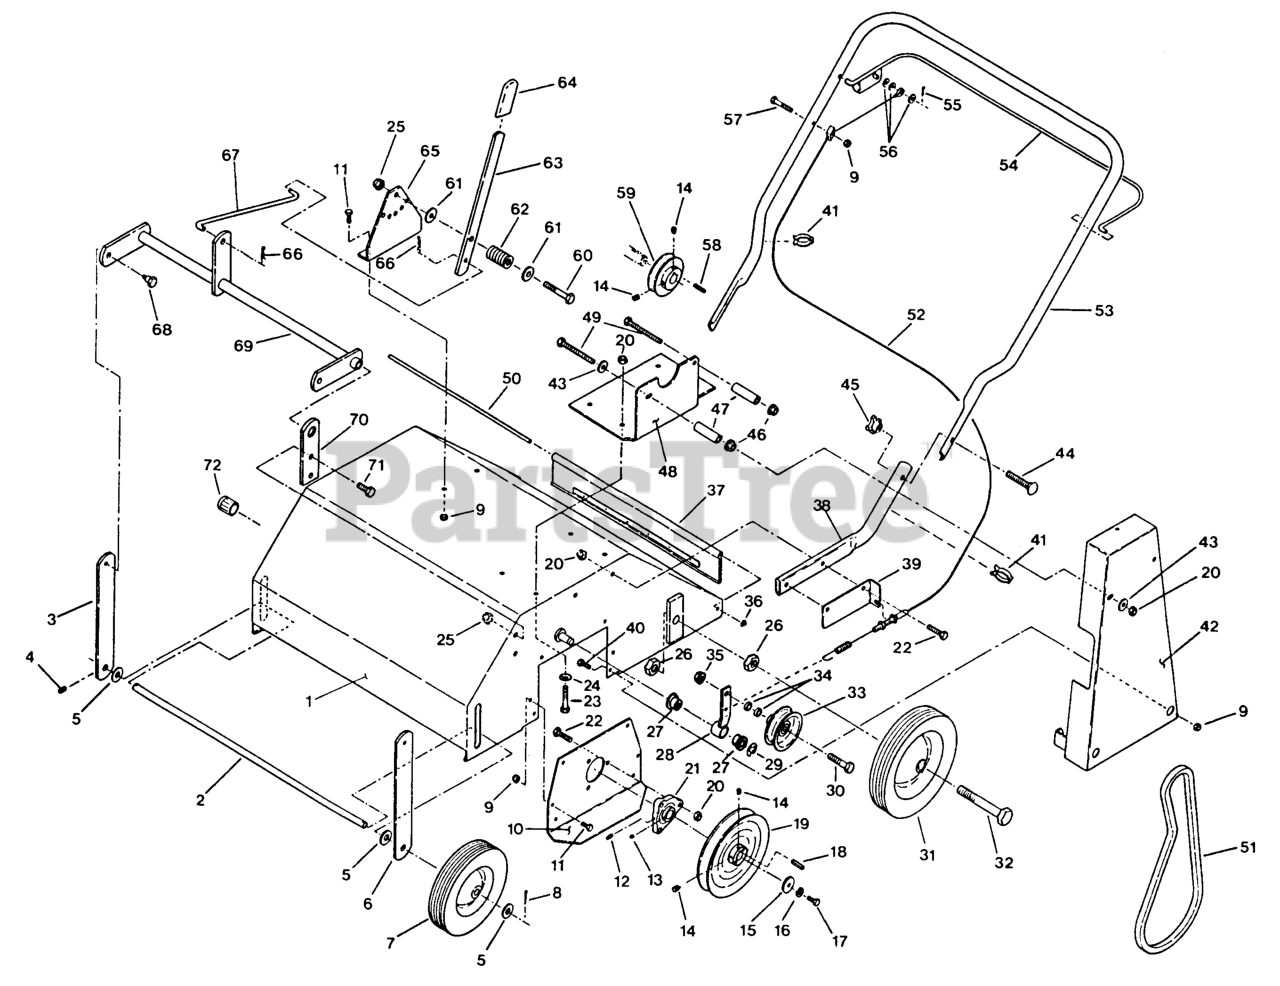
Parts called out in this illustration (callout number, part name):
7	ASM,WHEEL & TIRE
14	SCREW-SET
15	WASHER-RETAINER, PULLEY
16	WASHER-LOCK
24	WASHER-SPRING
27	BEARING-CONTROL
31	ASM,WHEEL & TIRE
49	BOLT,TAP HH
62	SPRING-COMPRESSION
64	GRIP-LEVER
66	PIN-COTTER
